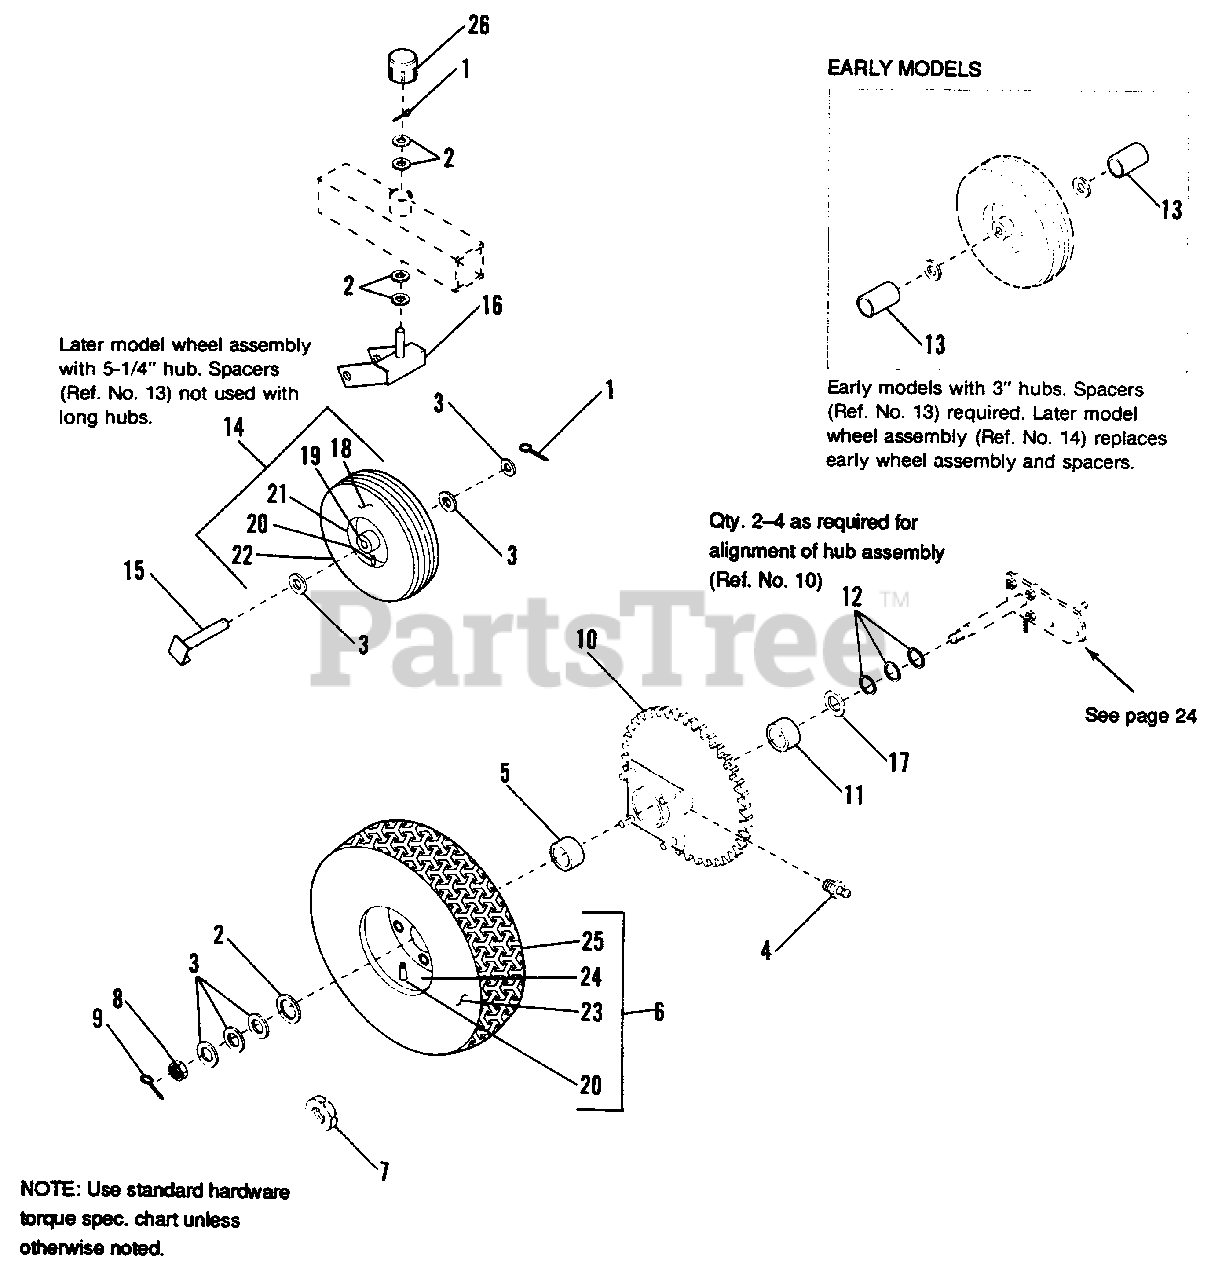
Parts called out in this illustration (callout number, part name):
1	COTTER PIN
2	WASHER, Plain
3	WASHER, Plain
4	FITTING, Grease
6	WHEEL AND TIRE ASSY., 18 x 9.50-8 (Includes Ref. Nos. 20 (Qty. 2), 23, 24, and 25)
7	NUT, Wheel 7/16-20
8	NUT, Hex, Slotted 3/4-16
10	HUB ASSY.
12	WASHER, Plain (As required for alignment)
13	SPACER, Caster (Early models only)
14	WHEEL AND TIRE ASSY., 13 x 5.00-6 (Includes Ref. Nos. 18,19, 20 (Qty. 2) 21, and 22)
16	CASTER ASSY.
17	WASHER, Plain
18	TUBE, (Used with Ref. No. 14)
19	BEARING, Flanged
20	VALVE STEM
21	WHEEL ASSY.
22	TIRE, 13 x 5.00-6
23	TUBE, (Used with Ref. No. 6)
24	WHEEL ASSY.
25	TIRE, 18 x 9.50-8
26	CAP, Threaded
